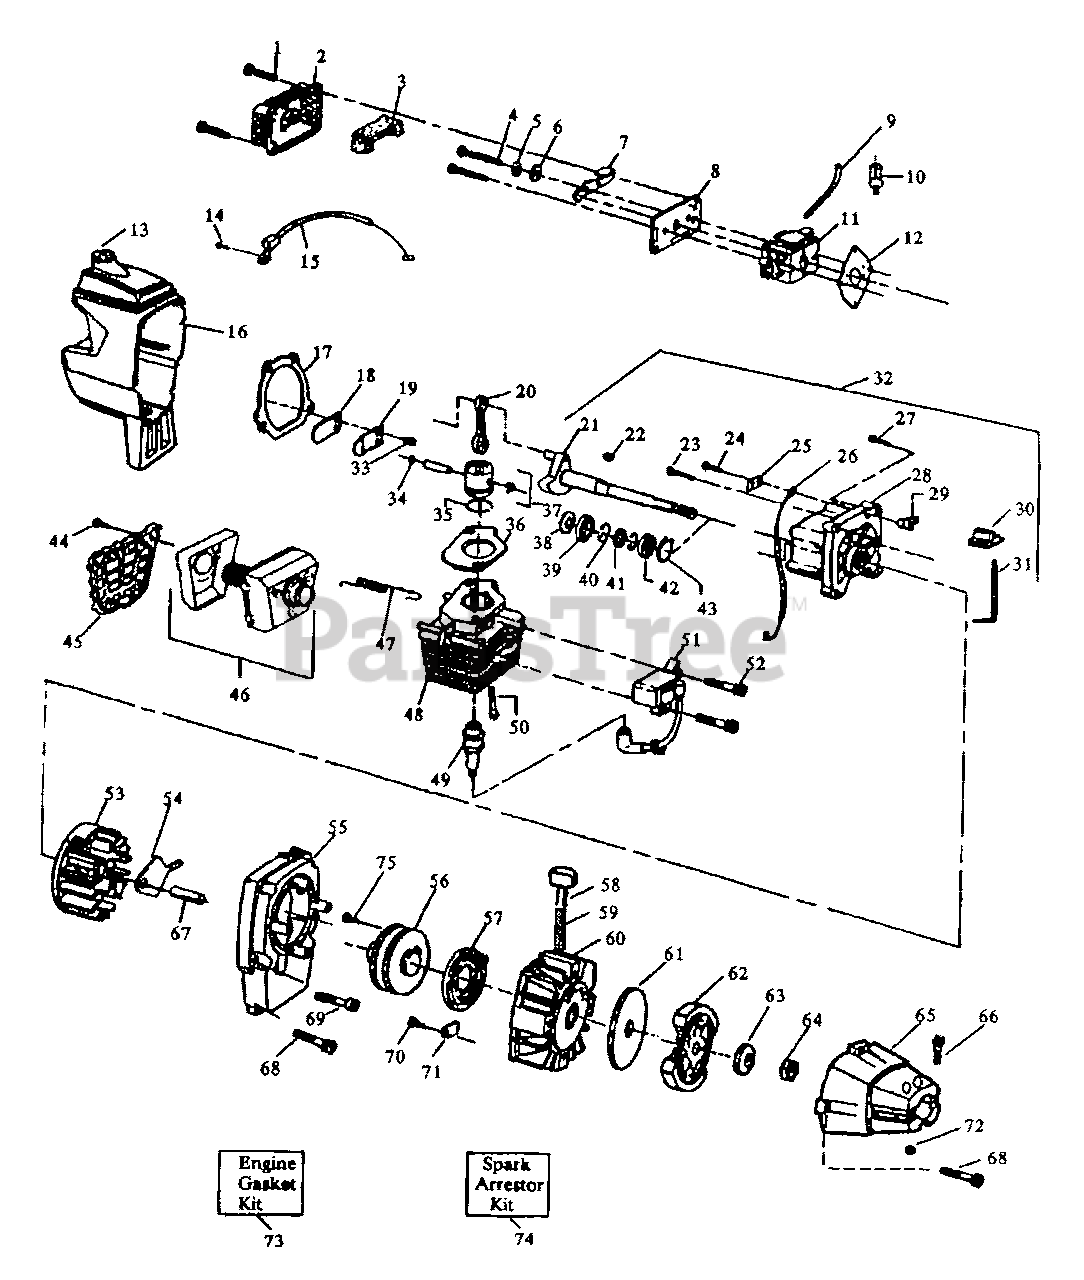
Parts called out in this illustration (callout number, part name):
2	Air Filter Cover
3	Air Filter
4	Screw
5	Spacer
6	Wave Washer
7	Choke Shutter
8	Air Filter Plate
9	Fuel Line Kit
10	Fuel Pick-up Ass'y.
11	Carburetor
12	Carburetor Gasket
13	Fuel Cap Ass'y.
15	Throttle Cable Ass'y.
16	Shroud & Tank Ass'y.
17	Crankcase/Shroud Gasket
20	Connecting Rod Ass'y.
21	Crankshaft Ass'y.
22	Flywheel Key
25	Kill Switch Insulator
28	Crankcase Ass'y.
29	Kill Switch Ramp
30	Kill Switch Button
31	Kill Switch Spring
32	Crankcase & Crankshaft Ass'y
33	Screw
34	Piston Pin Retainer
35	Piston Ring
36	Cylinder Gasket
37	Piston Kit
39	Inner Bearing
40	Retaining Ring
41	Crankshaft Seal
42	Outer Bearing
43	Crankshaft Retaining Ring
45	Muffler Guard
46	Muffler Kit
47	Muffler Attachment Spring
49	Spark Plug
51	Ignition Module Kit
53	Flywheel Ass'y.
54	Flywheel Counterweight
55	Fan Housing
56	Starter Pulley Kit
57	Starter Spring
58	Starter Handle
60	Pulley Housing Ass'y.
61	Clutch Washer
62	Clutch Ass'y. Kit
65	Clutch Housing
73	Engine Gasket Kit
74	Spark Arrestor Kit
75	Screw
